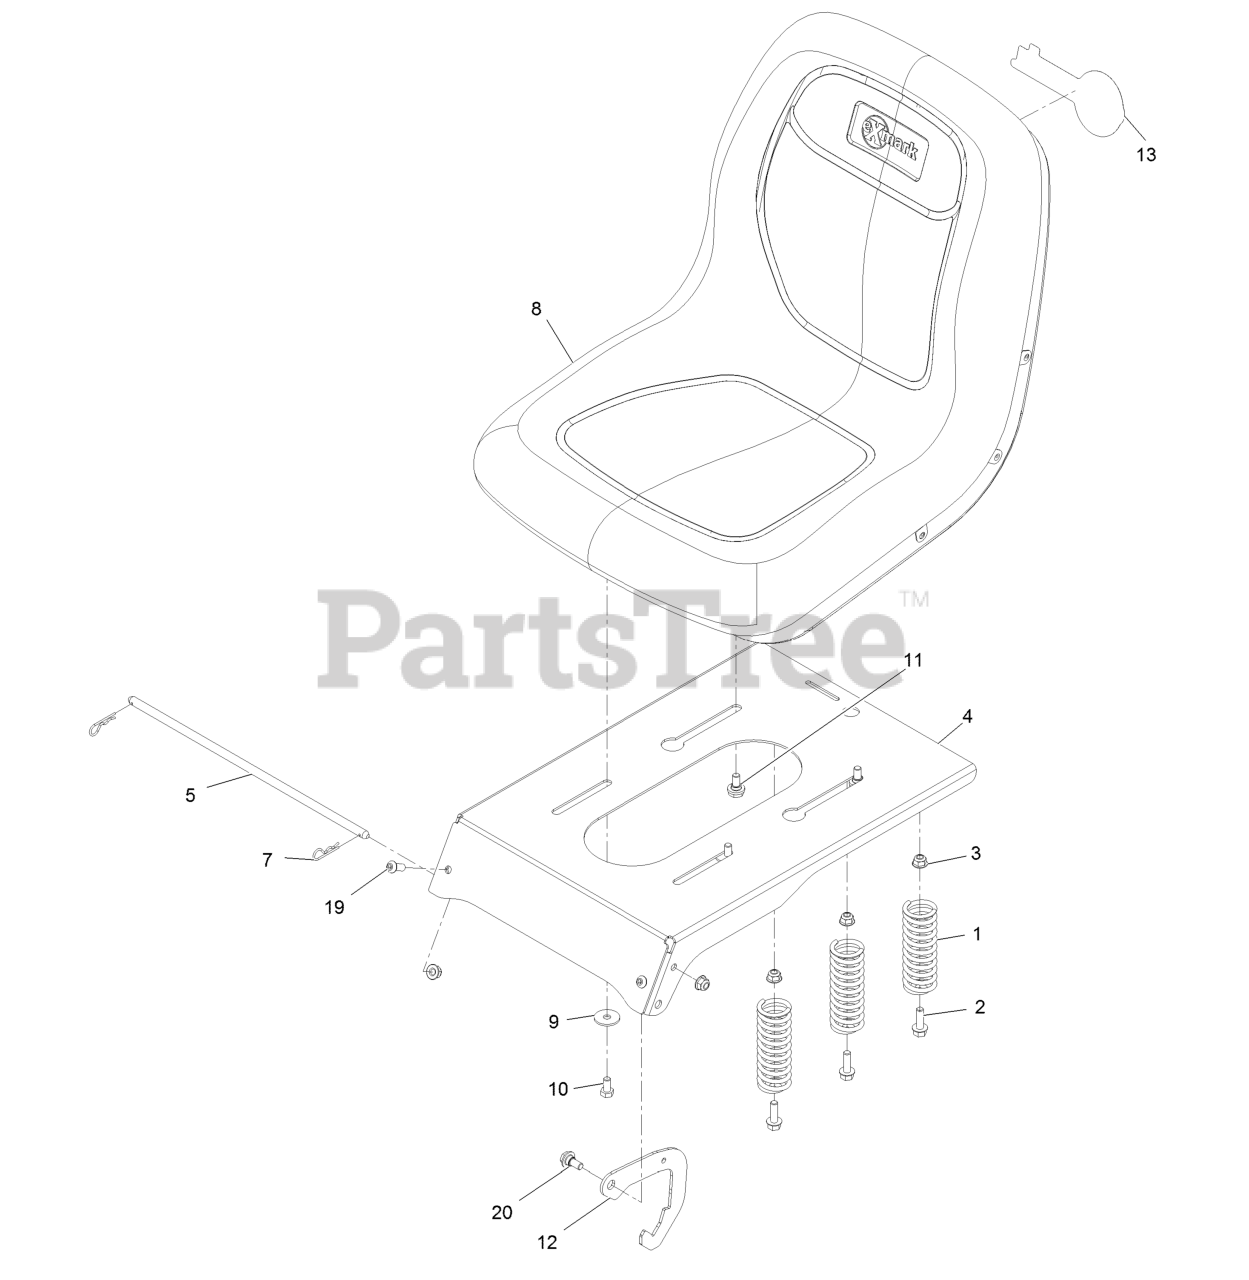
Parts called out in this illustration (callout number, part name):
1	SPRING-COMPRESSION
2	SCREW-HHF
3	NUT-HF, NI
5	ROD-PIVOT, NARROW
7	PIN-COTTER
8	SEAT-18 IN
9	WASHER-PIVOT
10	SCREW-HH
11	BOLT-SHOULDER,HFH
12	LATCH-SEAT
13	DECAL-EXMARK LOGO
19	SCREW-HSBH
20	SCREW-SHOULDER
